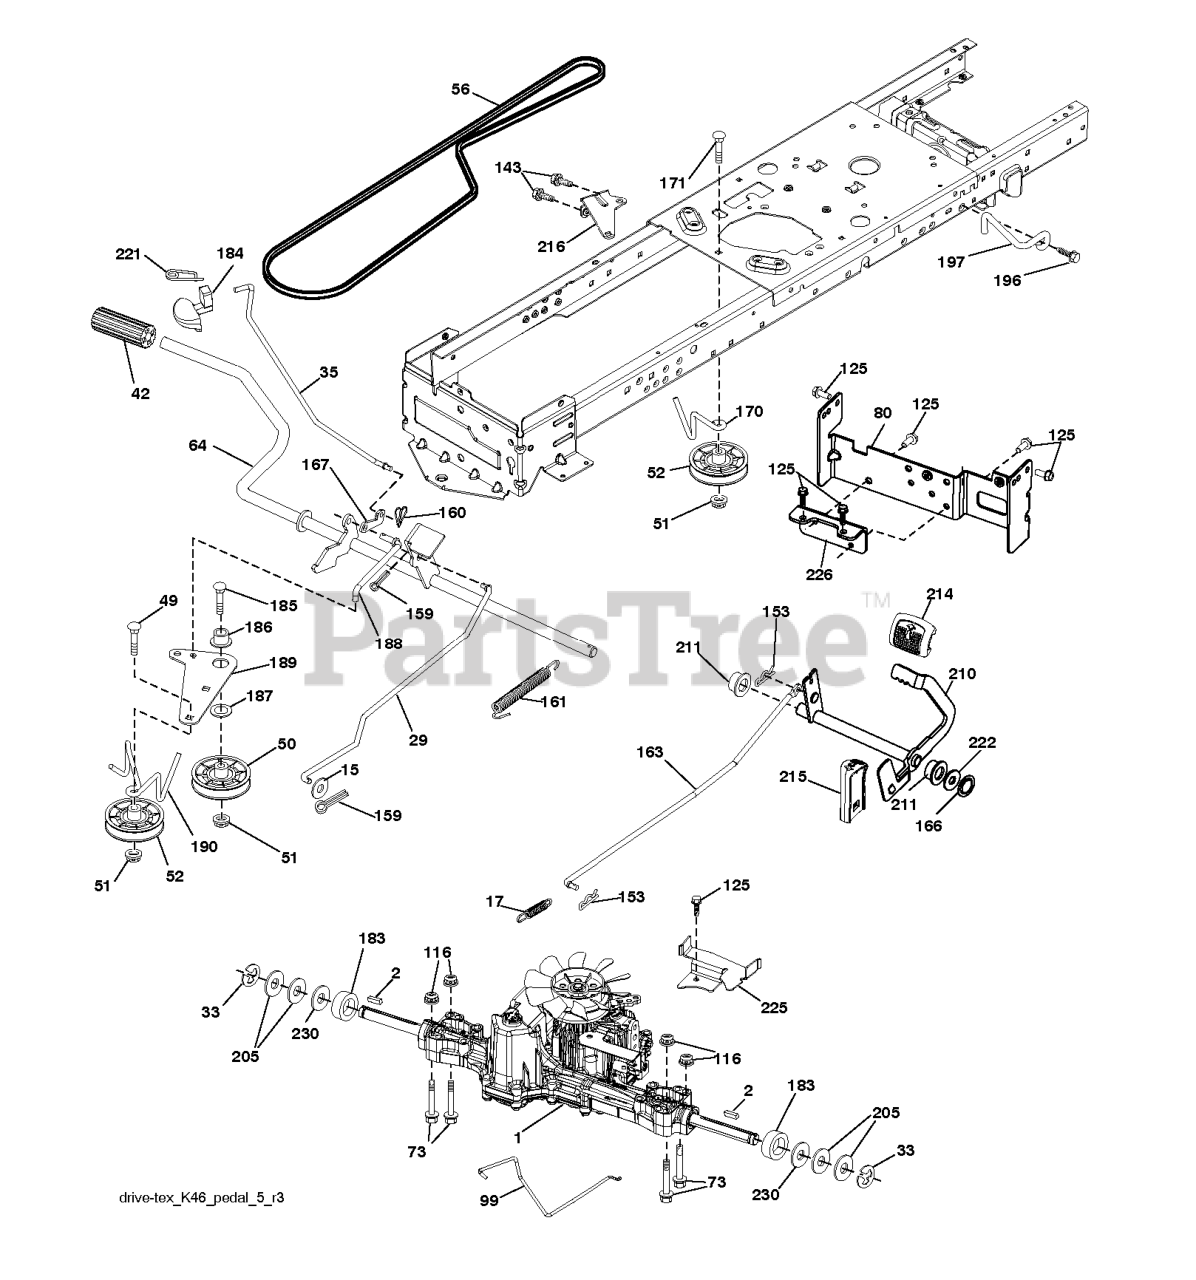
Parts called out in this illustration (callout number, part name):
1	THROTTLE CABLE
2	SCREW
4	MUFFLER.TWIN.CYL.LOW.TONE
5	EXHAUST TUBE LH KAWI
6	EXHAUST TUBE RH KAWI
8	BOLT.5/16-18UNCX3/4 W/SEMS.BLK
10	RP SHIELD HEAT MUFFLER
14	TUBE, DRAIN OIL ASM.
23	SHIELD.BROWNING.DBR.GUARD
25	REPL BY 532 1754-40
26	Nut Keps 3/8 - 24 UNF
29	KIT.SPARK ARRESTOR 794945 B&S
31	TANK FUEL
32	FUEL CAP
33	HOSE CLAMP
37	LINE.FUEL.20
44	SCREW HEXWSHR 1/4-20X3/4
45	SCREW, 3/8-16X3/4
81	NUT
101	NUT.HEX.FLANGE.TOPLOCK
105	SCREW 3/8-16X1
